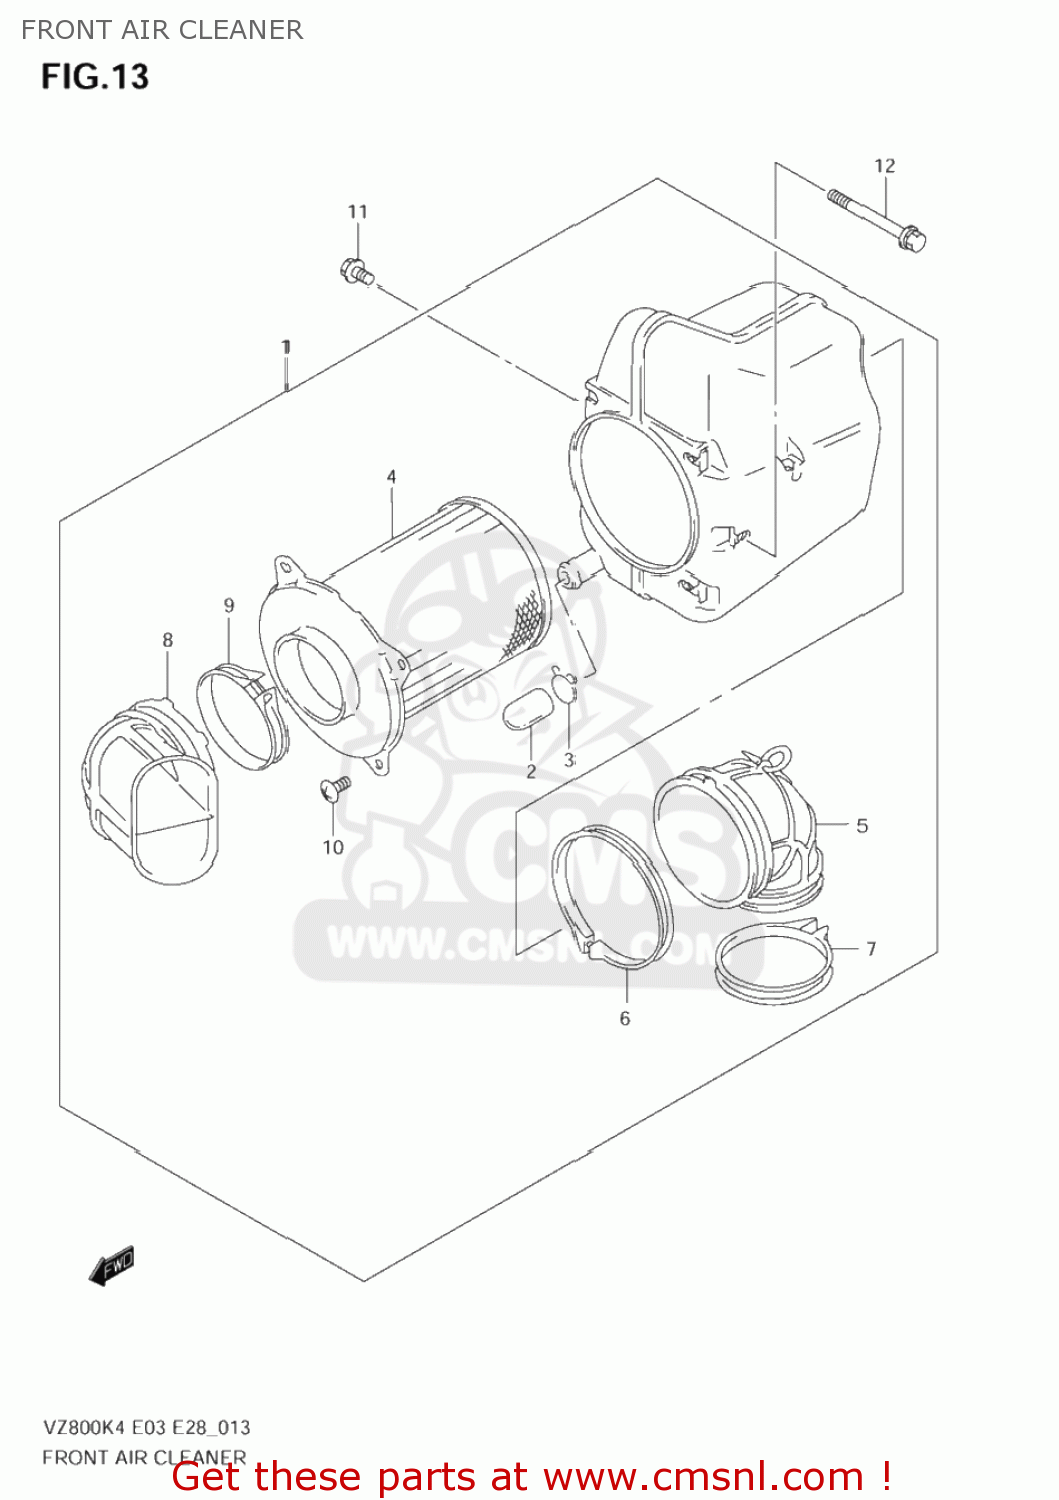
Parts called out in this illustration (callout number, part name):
1	CLEANER ASSY,AIR FR
2	PLUG
3	CLIP
4	FILTER ASSY
5	TUBE,AIR CLEANER OUTLET
6	CLAMP
7	CLAMP
8	TUBE,INLET
9	CLAMP
10	SCREW
11	SCREW 6X12
12	SCREW
